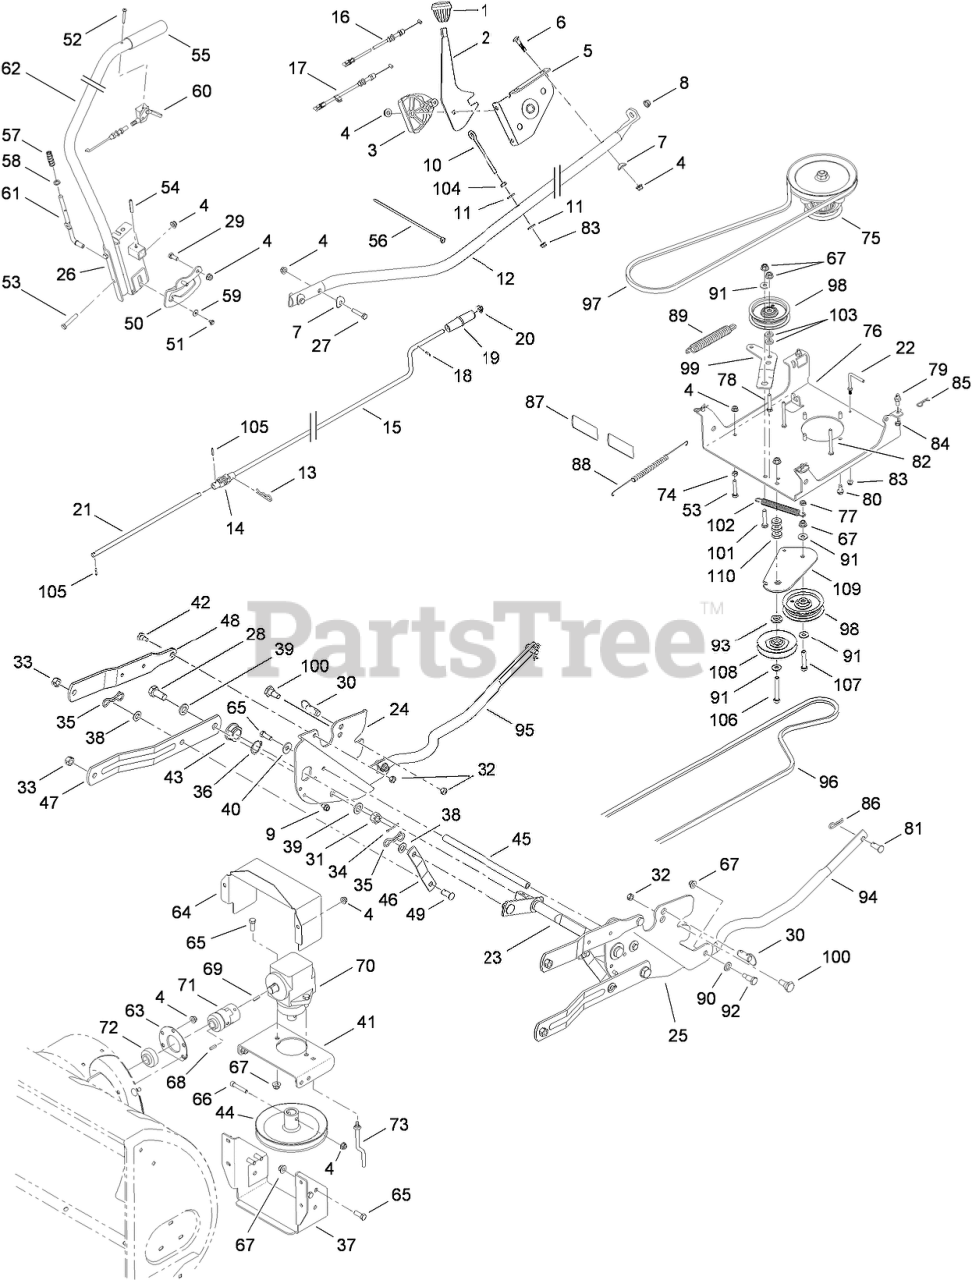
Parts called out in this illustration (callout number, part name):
2	HANDLE-TILT, CHUTE
3	GUIDE-CABLE
4	NUT-LOCK, FLANGE
5	BRACKET-TILT, CHUTE
6	BOLT-CARR
7	WASHER-SADDLE
8	BUSHING
9	SCREW-HWH
10	BOLT-EYE
11	WASHER-SPRING
12	TUBE-SUPPORT, CHUTE
13	PIN-COTTER
14	JOINT BLOCK ASM
15	ROD-CRANK, CHUTE
16	CABLE-CHUTE
17	CABLE-CHUTE
18	PIN-ROLL
19	KNOB-CRANK, CHUTE
20	NUT-PUSH
22	PIN-KEEPER, BELT
23	ROD ASM
24	PLATE-RH MOUNTING
25	PLATE-LH MOUNTING
26	LIFT BRACKET ASM
27	SCREW-HH
28	SCREW-HH
29	SCREW-HH
30	PIN-RELEASE, QUICK
31	NUT-HEX CASTLE
32	NUT-LOCK
33	NUT-HEX, LOCK
34	PIN-COTTER
35	PIN-COTTER, BOW TIE
36	RING-SNAP
37	PLATE-SKID
38	WASHER-FLAT
39	WASHER-FLAT
40	WASHER-BELL
41	BRACKET-MOUNTING
42	BOLT-SHOULDER
43	BEARING-FLANGE
44	PULLEY-DRIVE
49	PIN-BRACKET, LIFT
50	BRACKET-LIFT
51	SCREW-WASHER, HEX INDEX
52	SCREW-PAN HD
53	BOLT-HH
54	PIN-ROLL
56	TIE-CABLE
57	SPRING-COMPRESSION
58	WASHER-FLAT
59	WASHER-FLAT
60	CABLE-LIFT, W/TRIGGER
61	ROD-INDEX, LIFT
62	TUBE-HANDLE, LIFT
63	HOUSING-BEARING
64	COVER-BELT
65	SCREW-HH
66	SCREW-HSH
67	NUT-LOCK, FLANGE
68	KEY-SQUARE
69	KEY-HI PRO
70	DRIVE-ANGLE, RIGHT
71	COUPLER-FLEXIBLE
72	BEARING-BALL (W/OUT COLLAR)
73	ROD-KEEPER, BELT
74	NUT-HEX
75	7 INCH PULLEY SPINDLE ASM
76	BRACKET-MOUNTING, PULLEY
78	SCREW-HH
80	SCREW-HWH
81	PIN-CLEVIS
82	KEEPER-BELT
83	NUT-LOCK, FLANGE
84	NUT-HEX, CENTER LOCK
85	PIN-HAIR
86	PIN-CLIP, INTERNAL
87	REFLECTOR
88	SPRING-EXTENSION
89	SPRING-EXTENSION
90	WASHER-FLAT
91	WASHER-ISOMOUNT
92	BOLT-SHOULDER
93	SPACER-SHOULDER
94	TUBE-SUPPORT, LH
95	TUBE-SUPPORT, RH
96	BELT-V
97	BELT- V TYPE
98	PULLEY-IDLER, 3.50 INCH
99	BRACKET-IDLER
100	BOLT-SHOULDER
101	SCREW-HH
102	SPRING-EXTENSION
103	WASHER-FLAT
104	NUT-HEX
105	PIN-SPIROL
106	BOLT-HEX
107	SCREW-HH
108	PULLEY
109	IDLER PIVOT ASM
110	SPACER
